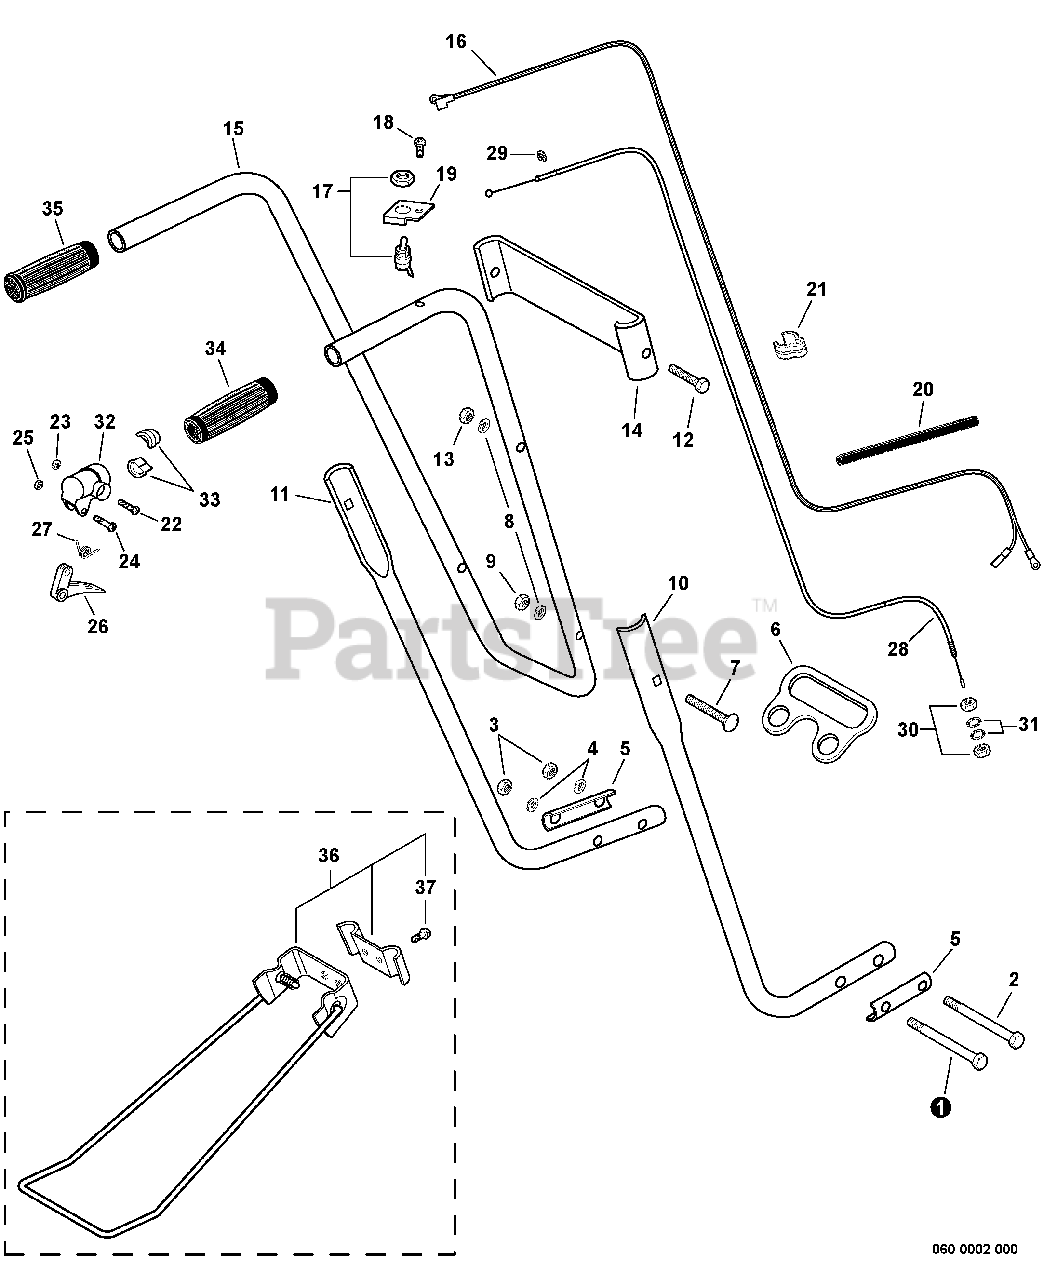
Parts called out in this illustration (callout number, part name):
1	BOLT - 1/4 X 3-1/4"
2	BOLT - 1/4 X 3"
3	LOCKNUT - 1/4"
4	LOCKWASHER
6	HANDLE, LIFTING
7	BOLT - 1/4 X 1-1/4"
8	LOCKWASHER
9	NUT - 1/4"
10	HANDLE, LOWER - RIGHT
11	HANDLE, LOWER - LEFT
12	BOLT - 1/4 X 1-1/4"
13	LOCKNUT - 1/4"
14	BRACKET, HANDLE
15	HANDLE - UPPER
16	LEAD, IGNITION SWITCH
17	IGNITION SWITCH KIT
18	SCREW - 5X10
19	BRACKET, SWITCH
20	TUBE - VINYL
23	LOCKNUT - 5
24	SCREW - 5X30
26	TRIGGER, THROTTLE
27	SPRING, TRIGGER
28	CABLE, THROTTLE
29	RING, RETAINING
31	LOCKWASHER - 6
32	BRACKET, TRIGGER
34	GRIP, HANDLE - RIGHT
35	GRIP, HANDLE - LEFT
36	KICK STAND KIT
37	BOLT - 6X12
